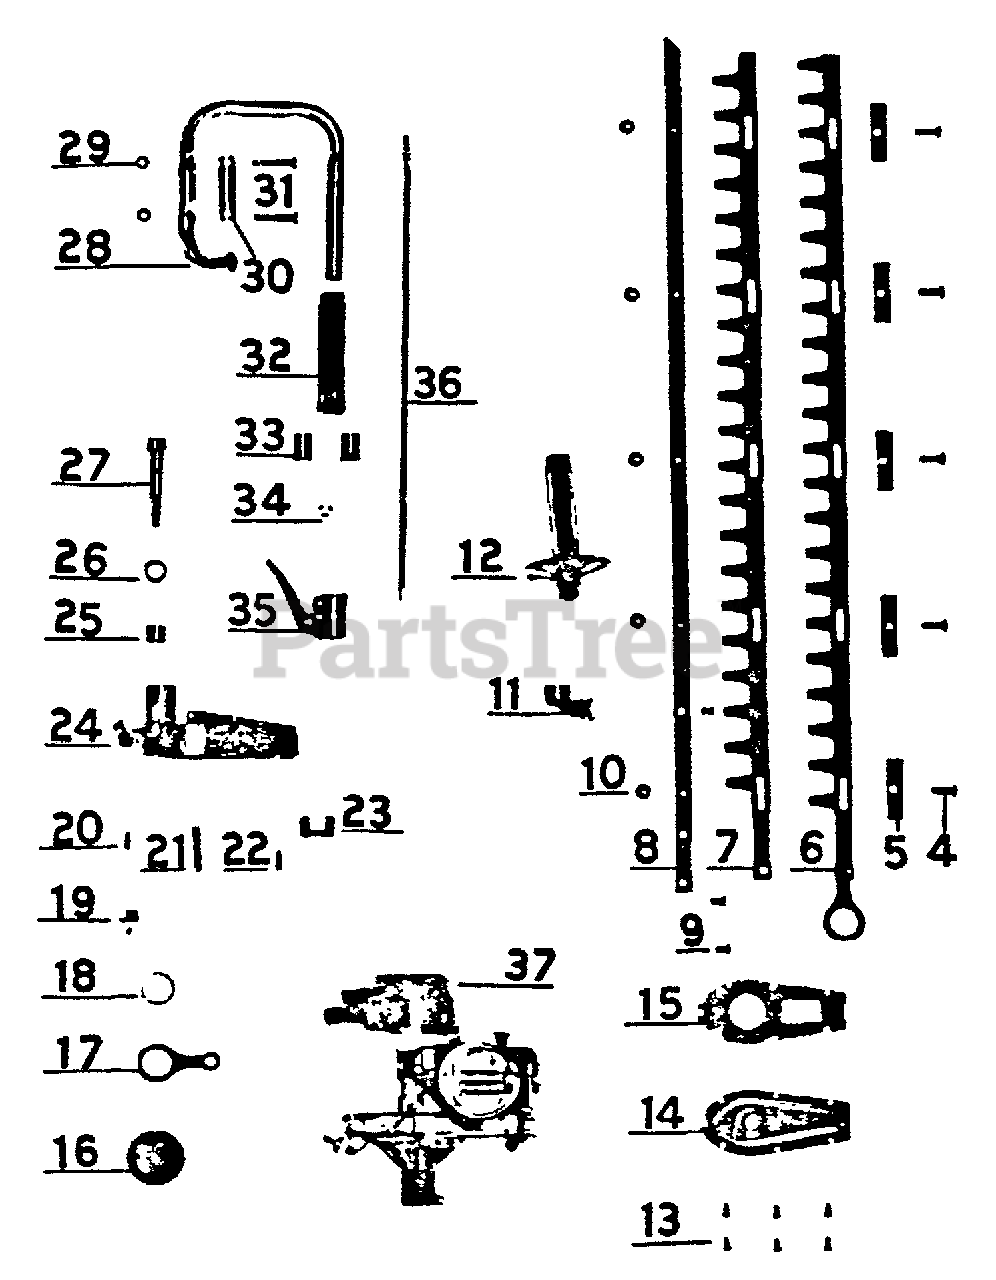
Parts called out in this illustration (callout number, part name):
4	SCREW - 1/4-28 X 11/16"
5	GUARD, BLADE
6	BLADE - 30" (76cm) -- OUTER
7	BLADE - 30" (76cm) -- INNER
8	STIFFENER, BLADE
9	SCREW - 1/4-28 X 1/2"
10	NUT - FLANGE
11	Handle Adapter
12	HANDLE - PLASTIC
13	SCREW
14	COVER, GEAR CASE
15	GASKET
16	ECCENTRIC GEAR
17	ROD, CONNECTING
18	SPACER
19	BUSHING - LOWER
20	PIN
21	SHAFT, ECCENTRIC
22	Wear Strip
23	SEAL, FELT
24	CASE, GEAR
25	BUSHING - UPPER
26	WASHER - 1/2"
27	GEAR - PINION
28	WASHER - 1/2"
28	HANDLE - REAR
29	NUT - 1/4-20 X 1-1/2"
30	CLAMP, HANDLE
31	BOLT - 1/4-20 X 1-1/2"
32	GRIP
33	RETAINER, CABLE
34	RING, RETAINING
35	LEVER, THROTTLE
36	CABLE, THROTTLE
37	KIORITZ ENGINE
